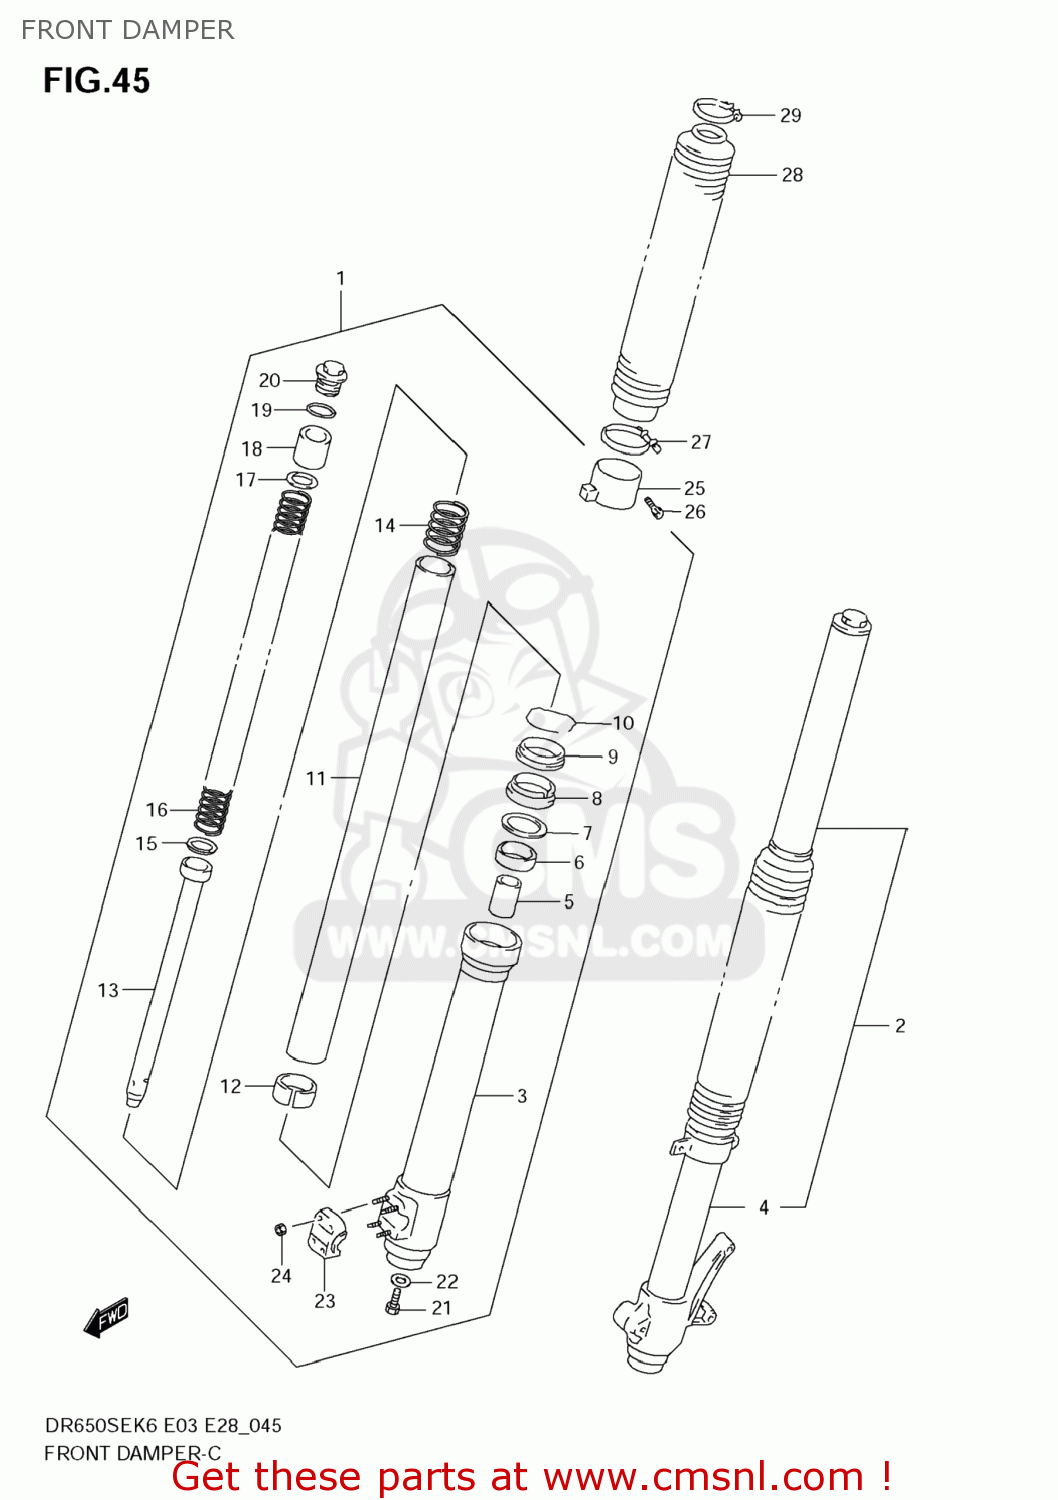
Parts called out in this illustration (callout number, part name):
1	DAMPER ASSY,FR FORK,R
2	DAMPER ASSY,FR FORK,L
3	TUBE,OUTER,R
4	TUBE,OUTER,L
5	PIECE,OIL LOCK
6	METAL,SLIDE
7	WASHER
8	SEAL,OIL
9	SEAL,DUST
10	RING,STOPPER
11	TUBE,INNER
12	PISTON
13	CYLINDER
14	SPRING,REBOUND
15	RING,PISTON
16	SPRING
17	WASHER
18	SPACER
19	O RING
20	CAP,FORK
21	BOLT,FORK CYLINDER(10X25)
22	GASKET (NAS)
23	HOLDER,AXLE,R
24	NUT
25	GUIDE,BOOT
26	BOLT
27	BAND,BOOT LWR
28	BOOT, BLACK
29	BAND,BOOT
